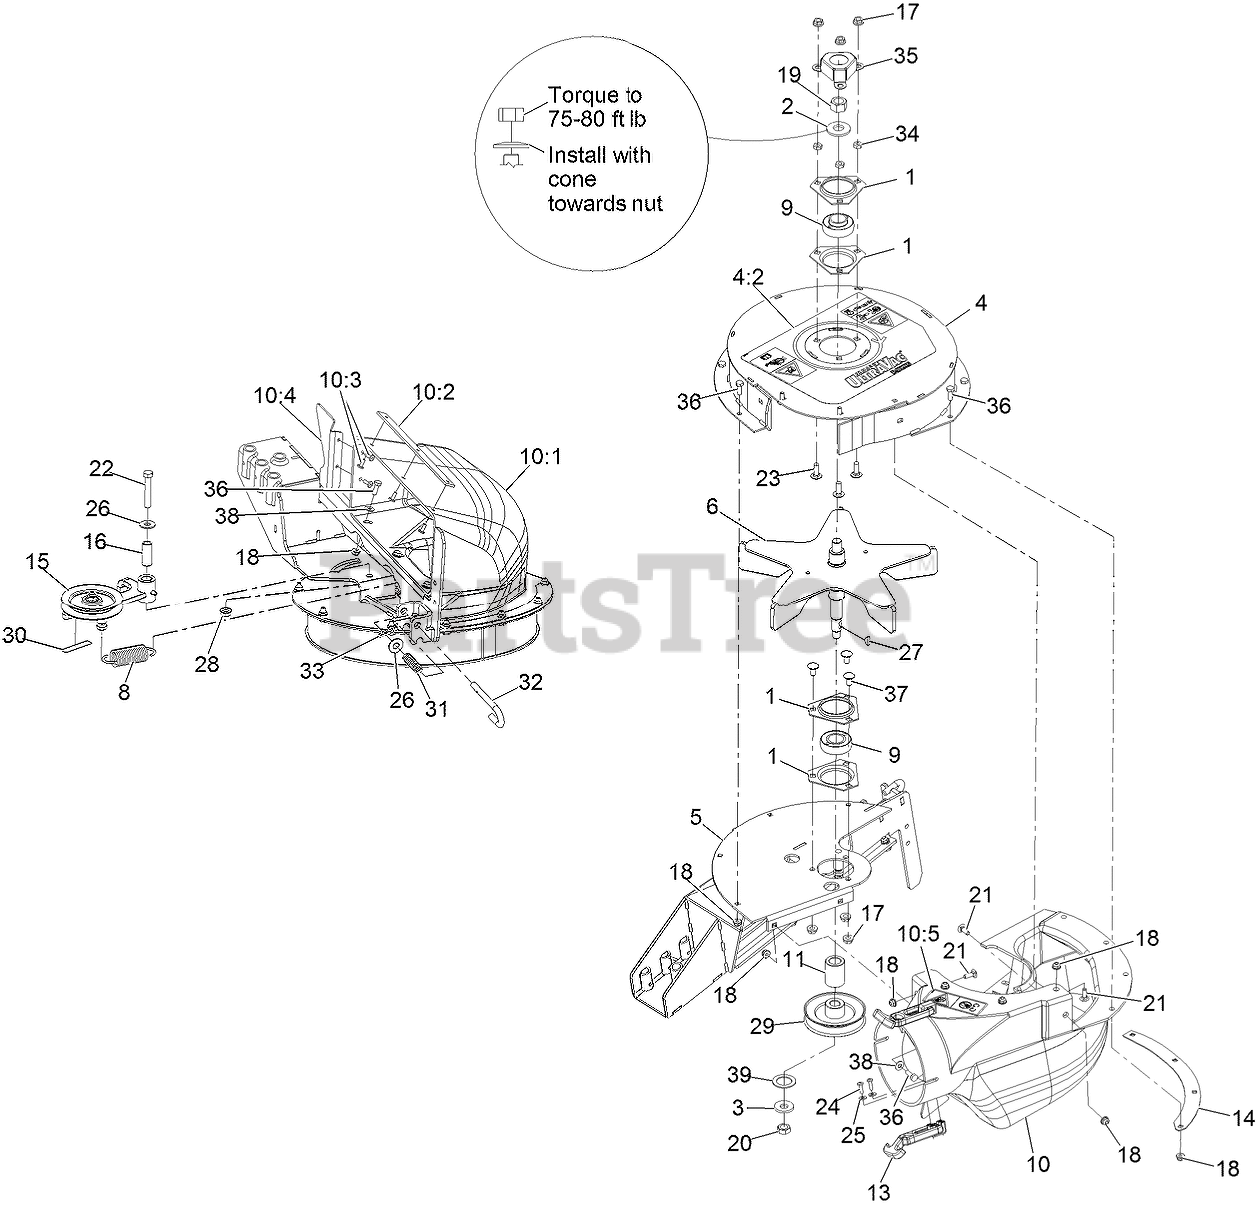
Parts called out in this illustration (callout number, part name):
1	HOUSING-FLANGE
2	WASHER-SPRING
3	WASHER-SPRING
4	UPPER HOUSING W/DECAL
4:2	Decal-Blower Warning
5	BLOWER FRAME ASM
6	IMPELLER
8	SPRING-IDLER
9	BEARING
10	BLOWER CHUTE ASM
10:1	CHUTE-BLOWER, SMALL
10:2	PLATE-REINFORCEMENT
10:3	RIVET-BLIND
10:4	PLATE-FILLER
10:5	Decal-Blower-Impeller Hazard
13	LATCH-RUBBER
14	PLATE-BACKING
15	ASM, Idler
16	BUSHING
19	NUT-HEX
20	NUT-JAM
21	BOLT-CARR
22	SCREW-HH
23	BOLT-CARR
24	SCREW-PPH
25	WASHER-FLAT
26	WASHER-FLAT
27	KEY-WOODRUFF
28	NUT-HHF, WHIZ
29	SHEAVE-BLOWER
30	DECAL-WARNING
31	SPRING-COMPRESSION
32	PIN-LATCH
34	NUT-JAM
35	COVER-NUT
36	SCREW-HH
37	SCREW-CARR
38	WASHER-FLAT
39	WASHER-SPACER
